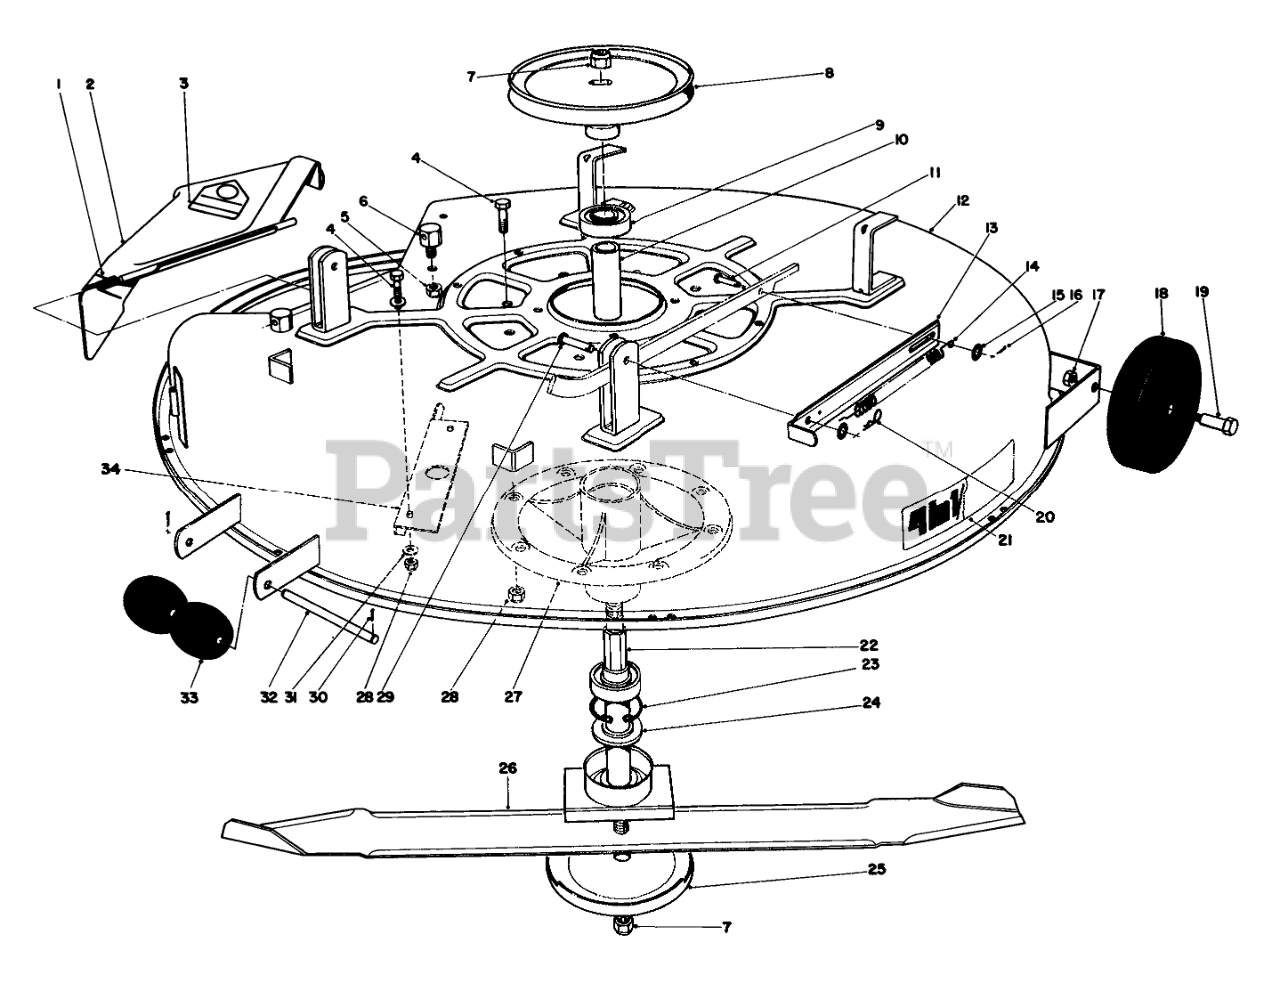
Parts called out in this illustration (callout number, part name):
1	SPRING
2	Deflector Assembly (Incl. Ref. #3)
3	DECAL-DANGER
4	SCREW-HH
5	NUT-LOCK, SIDE
6	POST-PIVOT
8	PULLEY(BLADE DRIVE)
9	BEARING-BALL
10	Spacer-Bearing
11	PIN-CLEVIS
13	DECK SPRING STRAP R
14	DECK TENSION SPRNG O
15	WASHER-FLAT
16	PIN-COTTER
17	NUT-LOCK, NI
18	WHEEL-DECK
19	BOLT-WHEEL
20	PIN-COTTER
21	DECK DECAL
22	SPINDLE SHAFT WA
23	RING-RETAINING
24	SPACER-SPINDLE
25	Cup
26	Blade
27	Spindle Body
28	NUT-LOCK, NI
29	PIN-CLEVIS
30	PIN-COTTER
31	WASHER-PLAIN
32	ROLLER SHAFT
33	ROLLER
34	Baffle Deck
